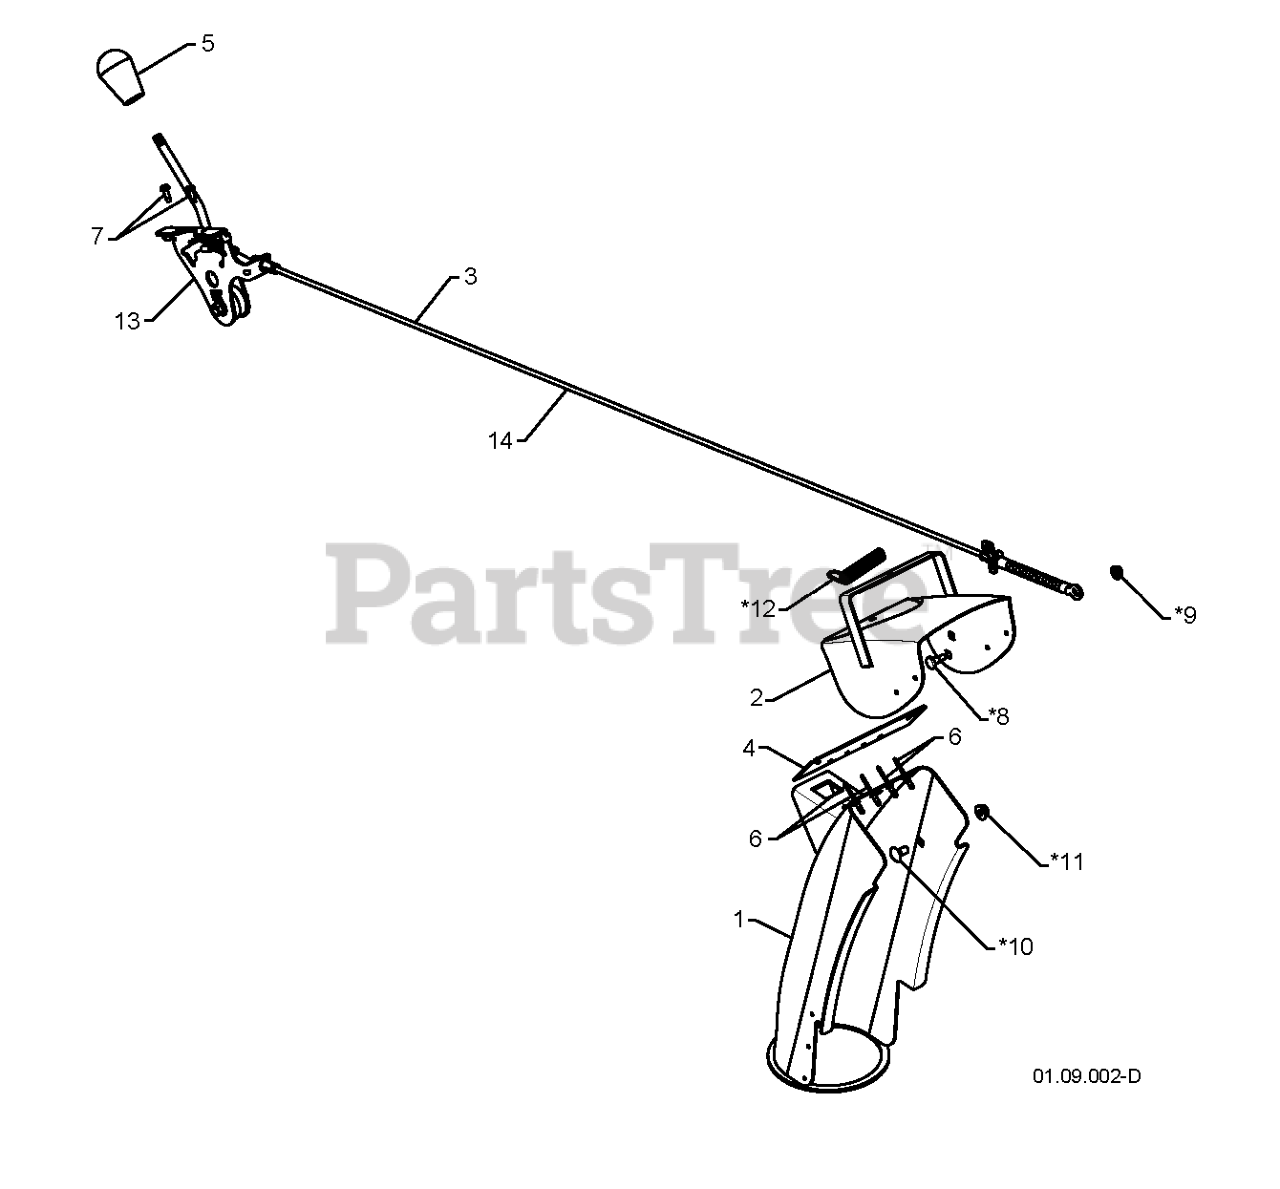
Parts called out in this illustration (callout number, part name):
1	CHUTE.WELDMENT
2	DEFLECTOR.WELDMENT.PNT.ORANGE
3	RP.CONTROL.ASM.DEFLECTOR.SNOW
4	SEAL.DEFLECTOR
5	KNOB LEVER, BLACK
6	RIVET BLIND
7	SCREW #10-24 X 5/8
13	RP CNTRL.HEAD.ASSEM.DEFLECTOR
14	RB SERVICE.CHUTE.DEF.CBL.BLK
